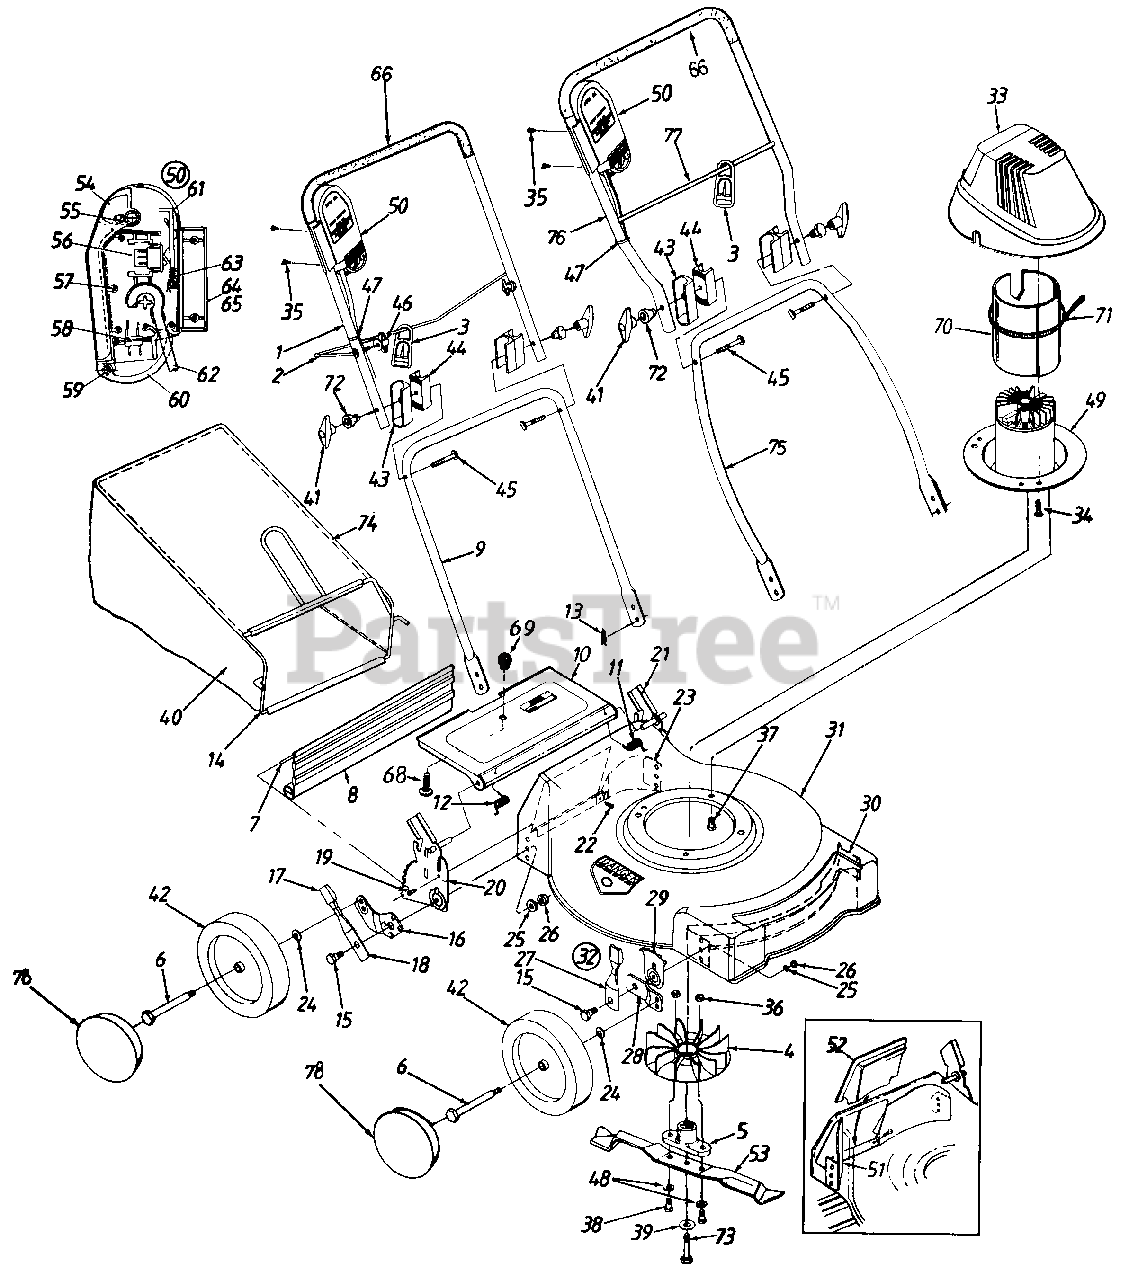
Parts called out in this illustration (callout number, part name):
3	Strain Relief - Cord
5	Blade Adapter
6	Axle Bolt
7	Rear Flap Wire
8	Rear Flap
12	Door Spring - R.H.
13	Hairpin Clip
16	Pivot Bar - R.H.
17	Spring Lever Knob
18	Spring Lever
19	Hex L-Wash. Hd. AB-Tap Scr. 1/4 x .62" Lg.
20	Handle Brkt. Ass'y.- R.M.
21	Handle Brkt. Ass'y.- L.H.
22	Torx . Mach. AB-Tap Scr. 1/4 x .62" Lg.
25	Bell-Wash .39" i.D. x 1.38" O.D.
26	Hex Nut 3/8-16 Thd.
27	Spring Lever Ass'y. w/Knob
29	Height Adj. Plate
33	Motor Cover
34	Scr. #10-16 x .75" Lg.
35	Self-Tap. Scr. #7 x 1" Lg.
36	Hex Nut 3/8-24 Thd.
37	Hex L-Wash. TT-Tap Scr. 3/8-16 x .75" Lg.
38	Hex Bolt 3/8-24 x 1.25" Lg.
39	Bell-Wash .396" I.D. x 1.14"
40	Grass Bag
41	Plastic Knob
42	Wheel Ass'y. Comp. (8" x 1.75")
43	Upper Handle Insulator
44	Lower Handle Insulator
45	Carriage Bolt 5/16-18 x 3" Lg.
46	Wing Nut 1/4-20 Thd.
47	Cable Tie
48	Bell-Wash. 3/8" I.D.
49	Motor, Cord & Switch Ass'y.
50	Cord & Switch Ass'y. Comp.
53	19" Blade
54	Handle - Switch Actuator
55	Spring - Switch Handle
56	Switch
57	Screw #6-32 x .5" Lg.
58	Plug Ass'y.
59	Retainer Plug Spring
60	Retainer Plug
61	Latch
62	Cord Ass'y.
63	Spring Latch
64	Housing - Upper Half
66	Foam Grip
68	Truss Scr. #10-24 x .38" Lg.
70	Insulator
71	Cable Tie
72	Insulator Knob
73	Hex Bolt 3/8-24 x 2.5" Lg.
77	Cord Control Rod
78	Hub Cap
